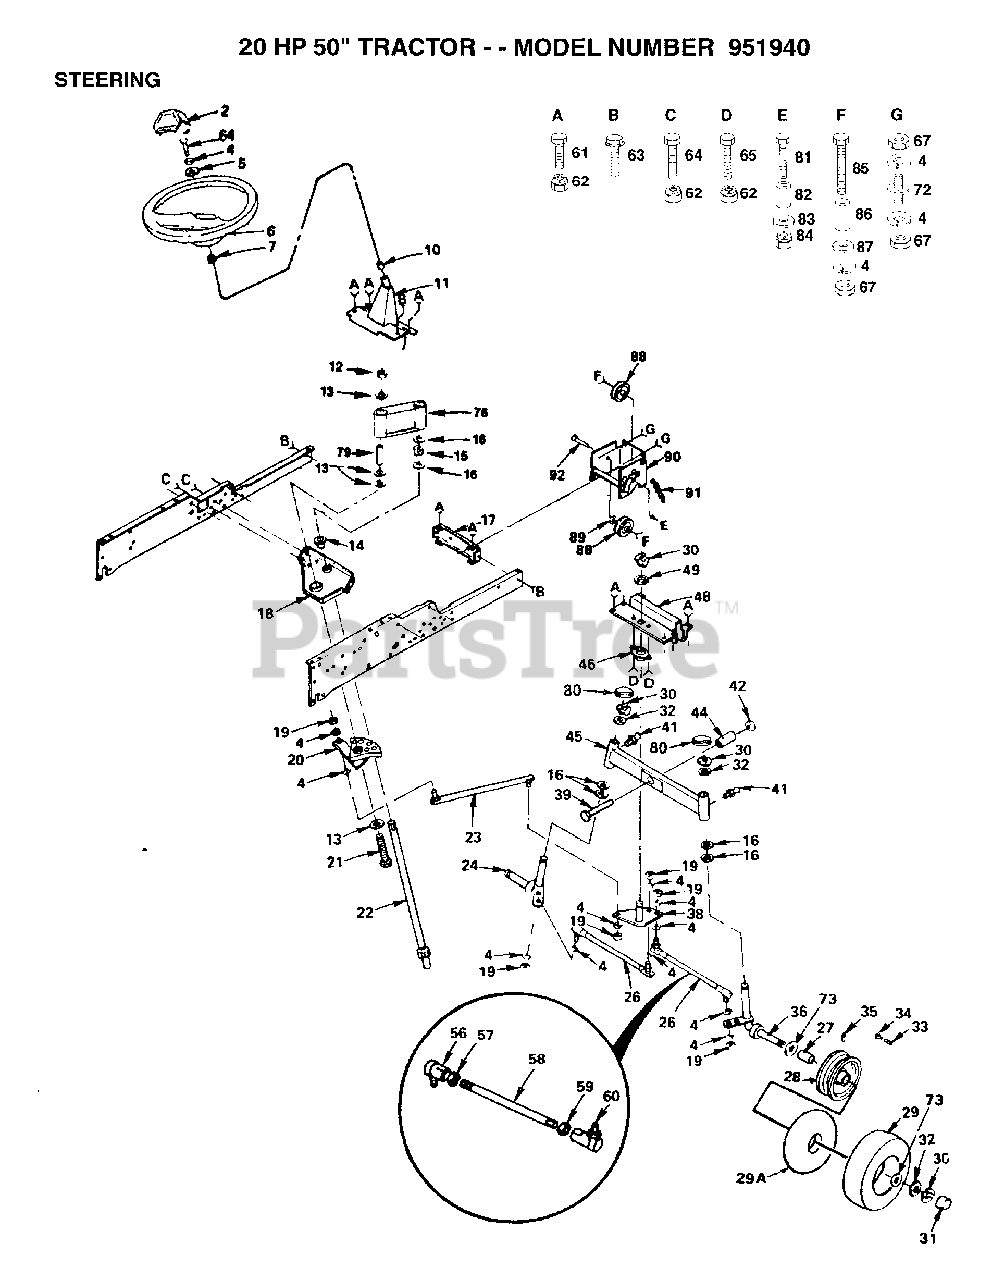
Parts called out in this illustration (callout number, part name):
2	INSERT STEERING
4	LOCKWASHER
5	WASHER T
7	ADAPTER LT
10	"T, BEARING"
11	SUPPORT ASSY T
12	NUT LTV
13	WASHER GT
14	"FLANGE GT, BEAR."
15	KLIP RING
16	WASHER .T
17	FRAME BRACKET GT
20	SECTOR T
21	BOLT T
22	SHAFT STEERING GT
23	LINK.DRAG.T
24	SPINDLE ASSY T
26	TIE ROD T
27	"FLANGE, BEARING"
29A	TUBE.16X6.5/7.5-8
30	RING
31	HUB CAP
32	WASHER
33	VALVE CAP
34	VALVE STEM LT
35	FITTING LT
36	SPINDLE RH T
38	"T, BELLCRANK"
39	BOLT
41	ZERK M
42	LOCKNUT M
44	SPACER BEARING
48	AXLE BRACKET T
49	WASHER
56	JOINT.LH
57	NUT
59	NUT
60	JOINT.RH
63	SCREW
64	BOLT
65	BOLT
67	NUT.HEX.3/8-16UNC
73	WASHER
76	COLLAR
79	TUBE T
80	CAP
82	SPLIT SPACER YTV
83	WASHER
85	BOLT
86	BUSHING LT
87	WASHER
88	IDLER-INSIDE T
89	WASHER T
90	IDLER BRKT T
91	SPRING
